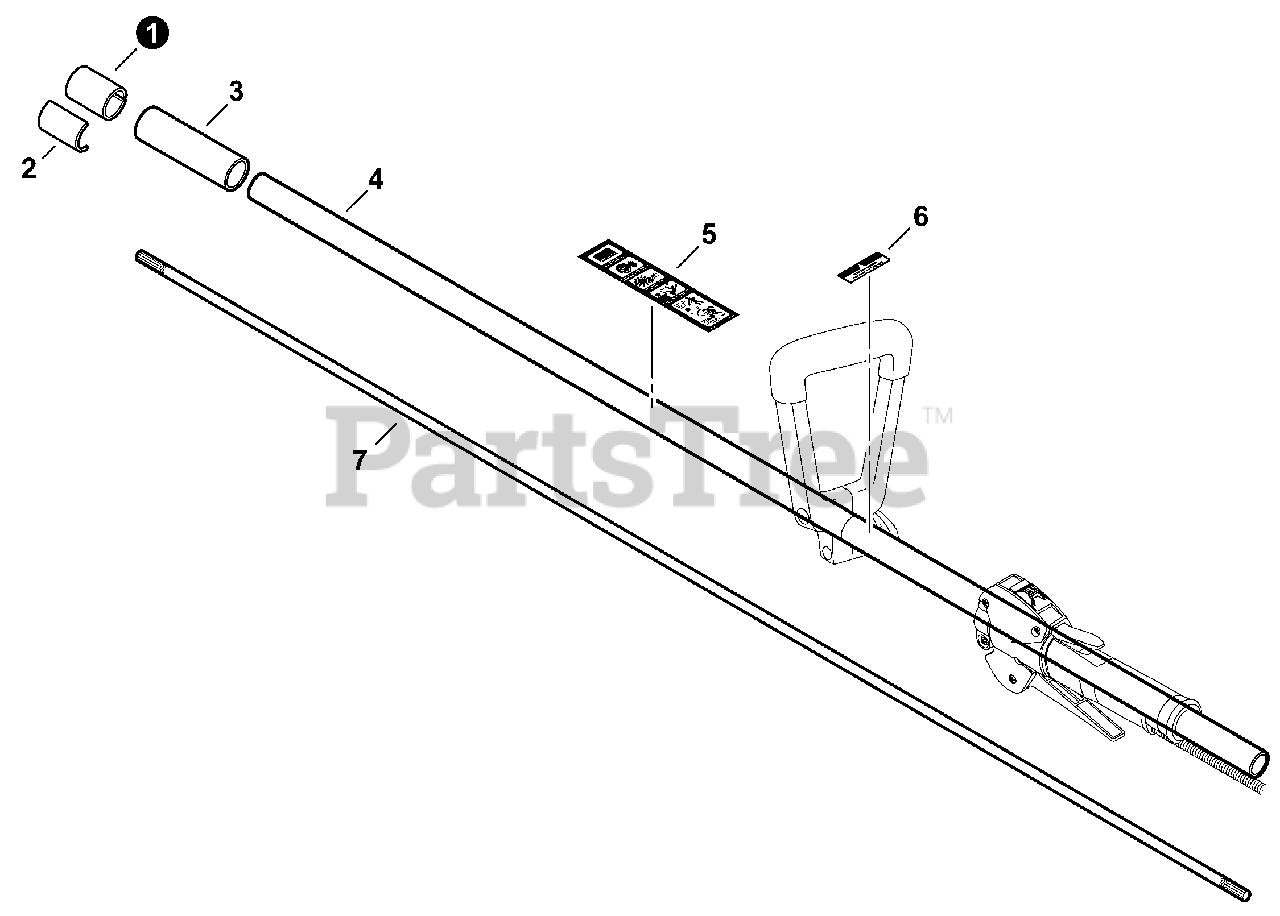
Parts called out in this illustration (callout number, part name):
1	COLLAR, PIPE
3	PROTECTOR, MAIN PIPE 25 MM
4	MAIN PIPE ASSY
5	LABEL, CAUTION
6	LABEL, HANDLE
7	MAINSHAFT
